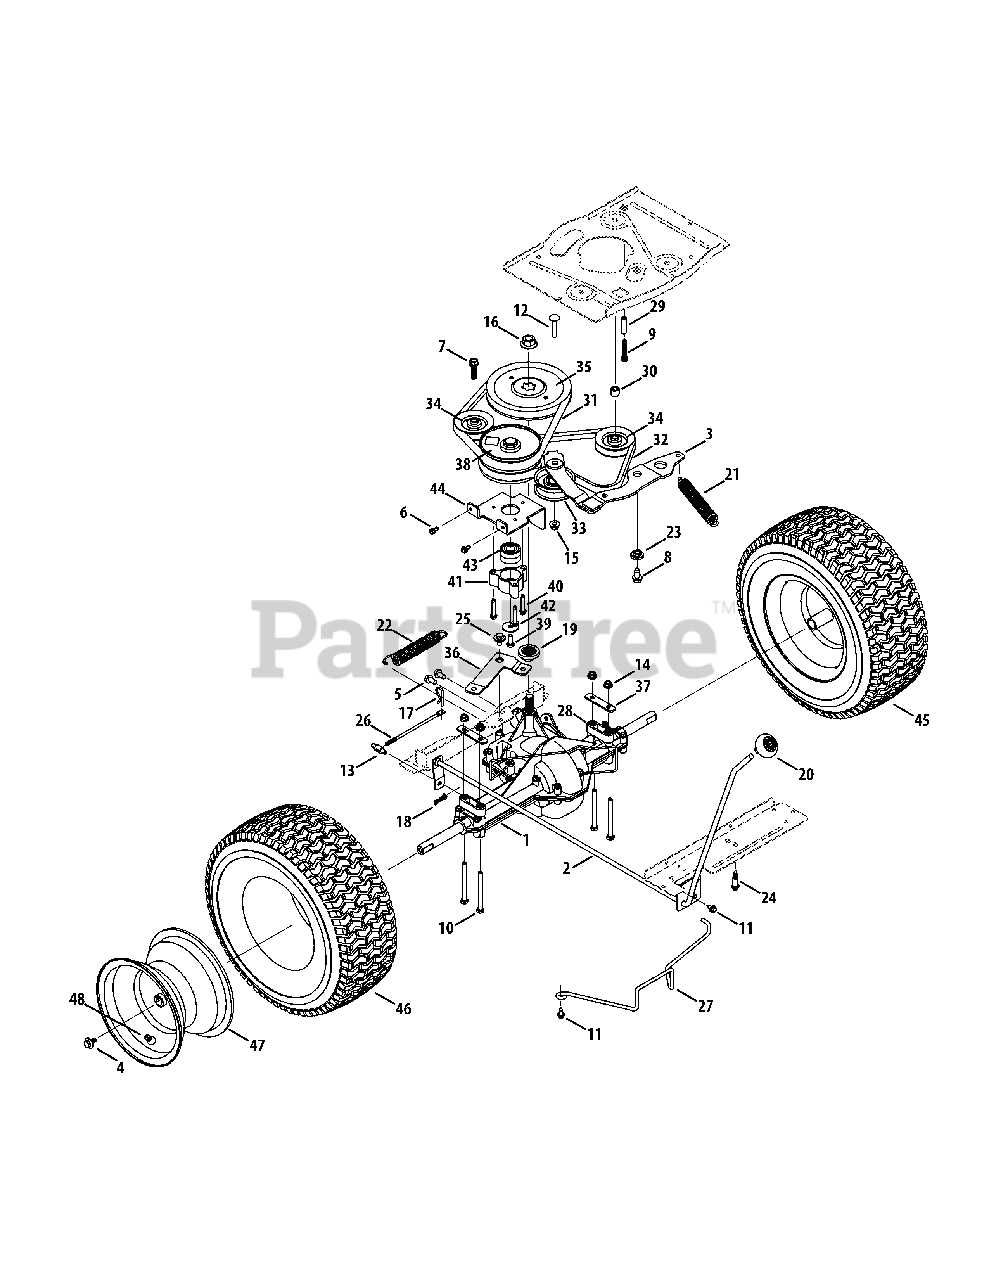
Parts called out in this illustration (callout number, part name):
1	Transmission Assembly
2	Shift Handle Assembly
3	Drive Assembly Idler
4	Beveled Washer .340 x .872 x .060
5	Tap Screw, 5/16-18 x .750
6	Tap Scew, 1/4-20 x 0.500
7	Screw, 3/8-16 x 1.375
8	Tap Screw, 3/8-16 x 0.750
9	Screw, 1/4-20 x 1.750
10	Hex Cap Screw, 5/16-18 x 3.5, Gr5
11	Tap Screw, 1/4-20 x .625
12	Screw, Carriage: 3/8-16 x 1.75"
13	Adjustable Ferrule, 1/4-20 x 1.00
14	Tap Screw, 1/4-20 x 1.0
15	Flange Lock Nut x 3/8-16
16	Flange Nut, 9/16-18
17	Internal Cotter Pin .125 Dia.
18	Bow-Tie Cotter Pin
19	Pulley Hub, 5/8 Spline
20	Shift Knob
21	Extension Spring .94 Dia. 6.74 Lg.
22	Extension Spring .97 OD x 6.18
23	Shoulder Spacer 1.00 x .38 x .38
24	Shoulder Screw, .368 x .75, 1/4-20
25	Shoulder Screw, .560 x .165, 5/16-18
26	Shift Rod
27	Deck Belt Keeper, 30"
28	Spacer
29	Spacer, .385 x .625 x .500
30	Spacer, .406 ID x 1.00 OD x .38
31	V-Belt, 5L:35.25
32	V-Belt, 5L:35.28
33	Flat Idler Pulley 2.75 OD
34	V-Type Idler Pulley 3.06
35	V-Type Pulley 6.56
36	Rear Idler Arm Bracket
37	Transaxle Mounting Bracket
38	Variable Speed Pulley Assembly
39	Hex Head Lock Screw 5/16-24 x .750
40	Tap Screw 1/4-20 x 1.500
41	Bearing Cup
42	Flat Washer .330 x 1.250 x .060
43	Ball Bearing, 17 x 40 x 12
45	Complete Wheel Assembly
46	Tire 16 x 6.5 x 8 Sq. Shldr.
47	Rim Assembly 8,0 x 5,38
48	Air Valve
